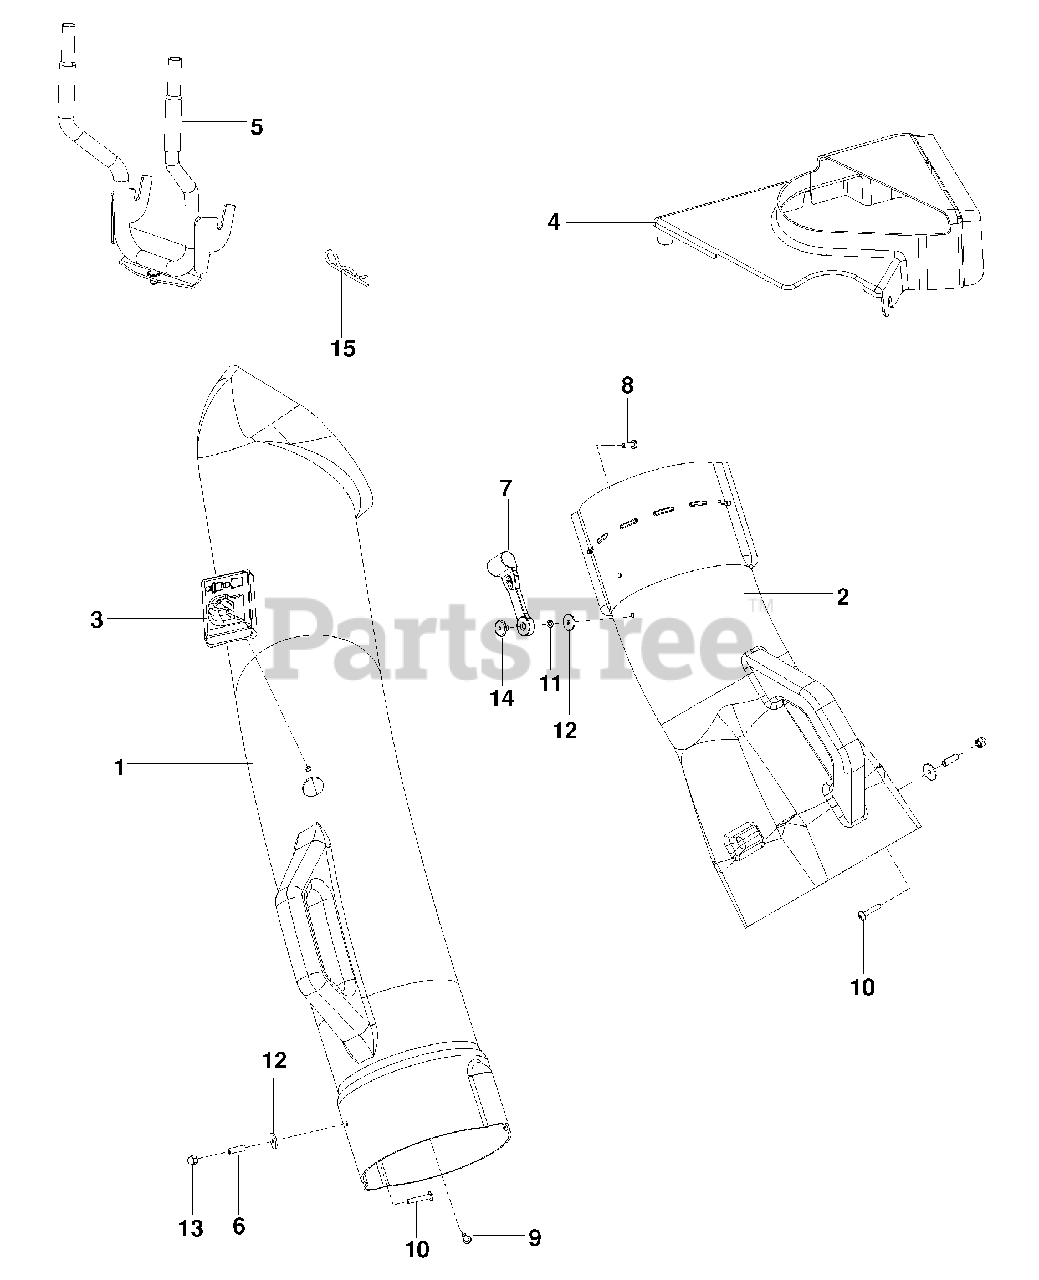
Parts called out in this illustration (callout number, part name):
1	Chute, Upper
2	Chute, Middle
3	Indicator, Bag Dump
4	Shield, Belt
5	Support Tube Assy
6	Spacer, Split
7	Latch, Chute
8	Screw 10-24 X .625 Mach
9	Screw 10-14 X 1/2 Spec
10	Screw 10-24 X 11/8
11	Washer 3/16 Lock
12	Washer 3/16 X 3/4
13	Nut 10-24 Acorn
14	Weld Nut, Plated
